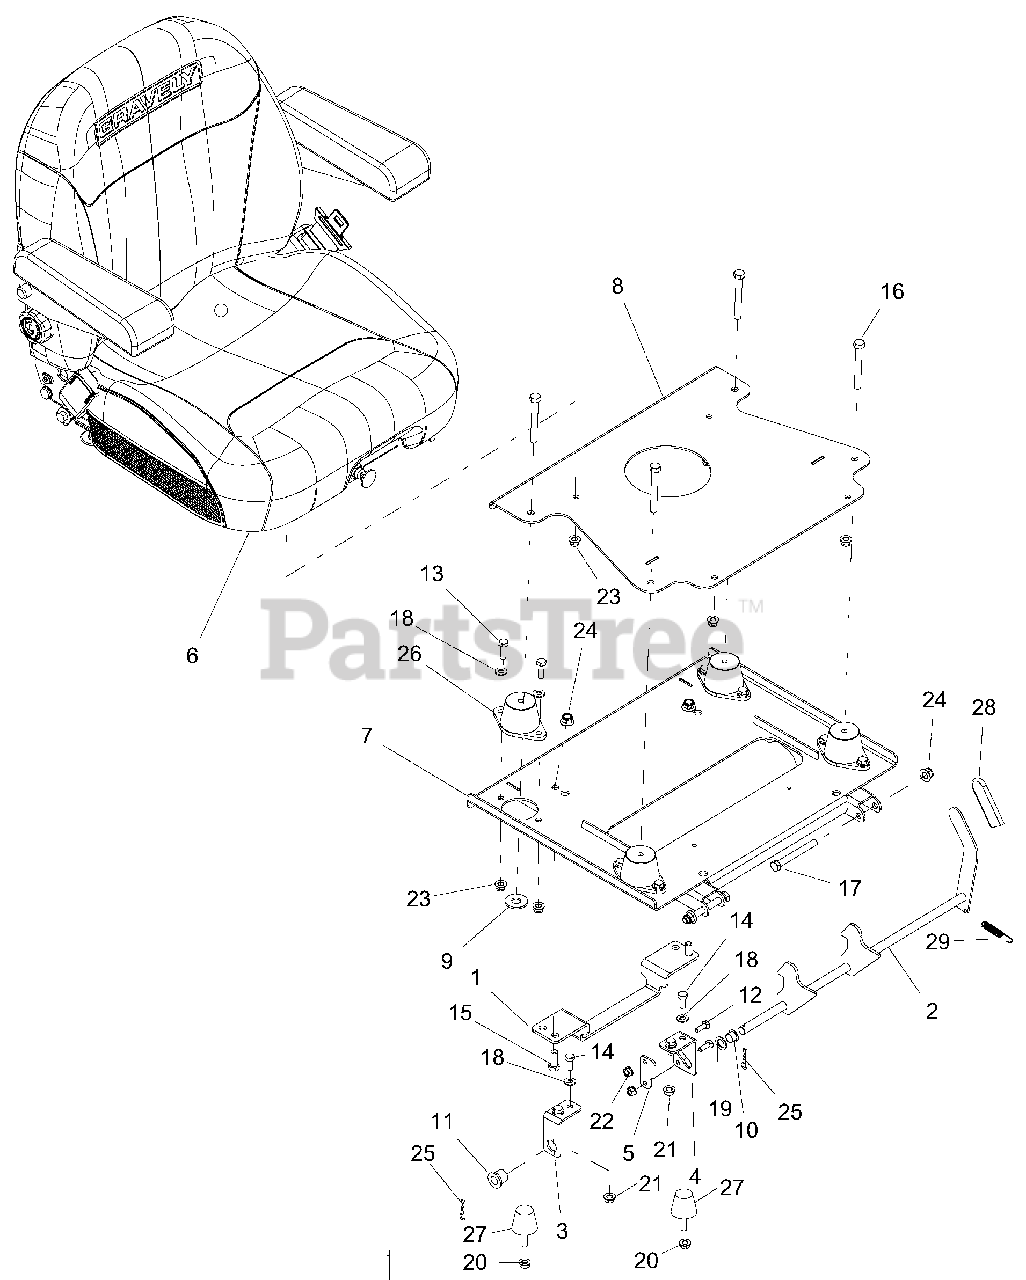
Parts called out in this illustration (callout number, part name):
1	BRKT, SEAT LATCH
2	WMT, SEAT LATCH
3	MOUNT, SEAT LATCH - RH
4	MOUNT, SEAT LATCH - LH
5	RETAINER-SEAT LATCH
6	SEAT, AIR SUSPENSION
7	WLDMT, SEAT ISO MOUNTING
8	WLDMT, SEAT MOUNTING
9	WLDMT, SEAT RETAINER
10	BSHG, SPLIT NYLON
11	BUSHING, FLANGE NYLON
12	BLT-HEX .25-20X.75 GR5 YWZC
13	BLT-HEX .31-18X1.00 GR5 YWZC
14	BLT-HEX .31-18X.75 GR5 YWZC
15	BLT-HEX .38-16X1.00 GR5 YWZC
16	BLT-HEX .38-16X3.0 GR5 FTD YWZ
17	BLT-HEX .38-16X3.25 GR5 YWZC
18	WSHR-FL-STL.344X.688X.065YWZC
19	WSHR-FL-STL .520X.827X.062 YWZC
20	NUT-SPNLK-FLG .312-18 YWZC
21	NUT, LK-TOP-FLG .312-18 YWZC
22	NUT, LK-TOP-FLG .25-20 YWZC
23	NUT-LK-NYL-FLG .31-18 YWZC
24	NUT-LK-NYL-FLG .38-16 YWZC
25	PIN-HAIR INT .08X.38X1.42 YWZC
26	MOUNT, ISOLATOR
27	BUMPER, STUD MOUNTED CONE SHAPED
28	GRIP-VINYL-YELLOW .125 x 1.0 x 3.0
29	SPRG, TENSION .043X.44X3.31 WLD 5.8
